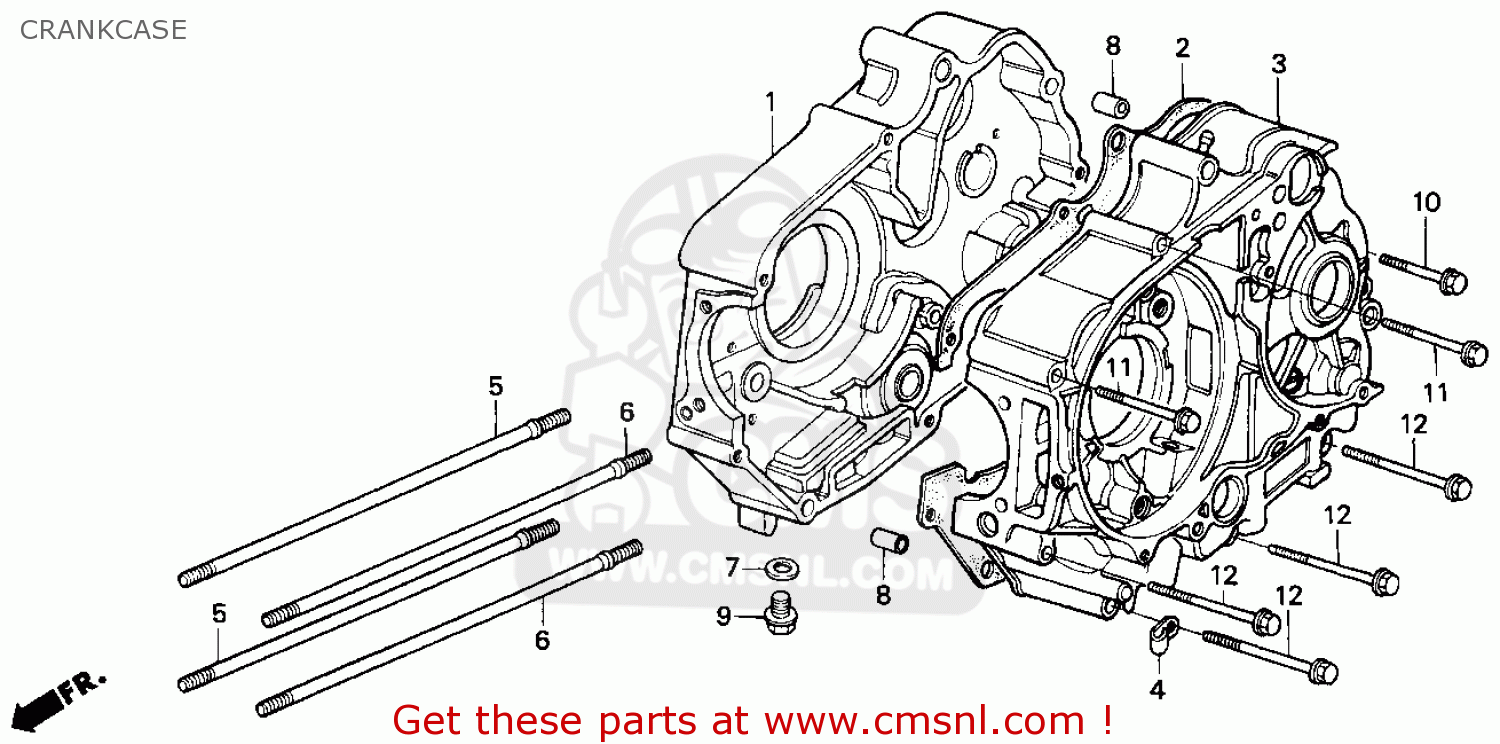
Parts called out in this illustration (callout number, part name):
1	CRANK CASE COMP,R
2	GASKET CRANK CASE (NAS)
3	CRANKCASE COMP.,L
4	STAY,OVERFLOW TUB
5	BOLT A CYLN STUD
6	BOLT B CYLN STUD
7	PACKING, COCK
8	DOWEL PIN
9	BOLT DRAIN 12MM
10	BOLT,FLANGE,6X50
11	BOLT,FLANGE,6X60
12	BOLT,FLANGE SH 6X65
